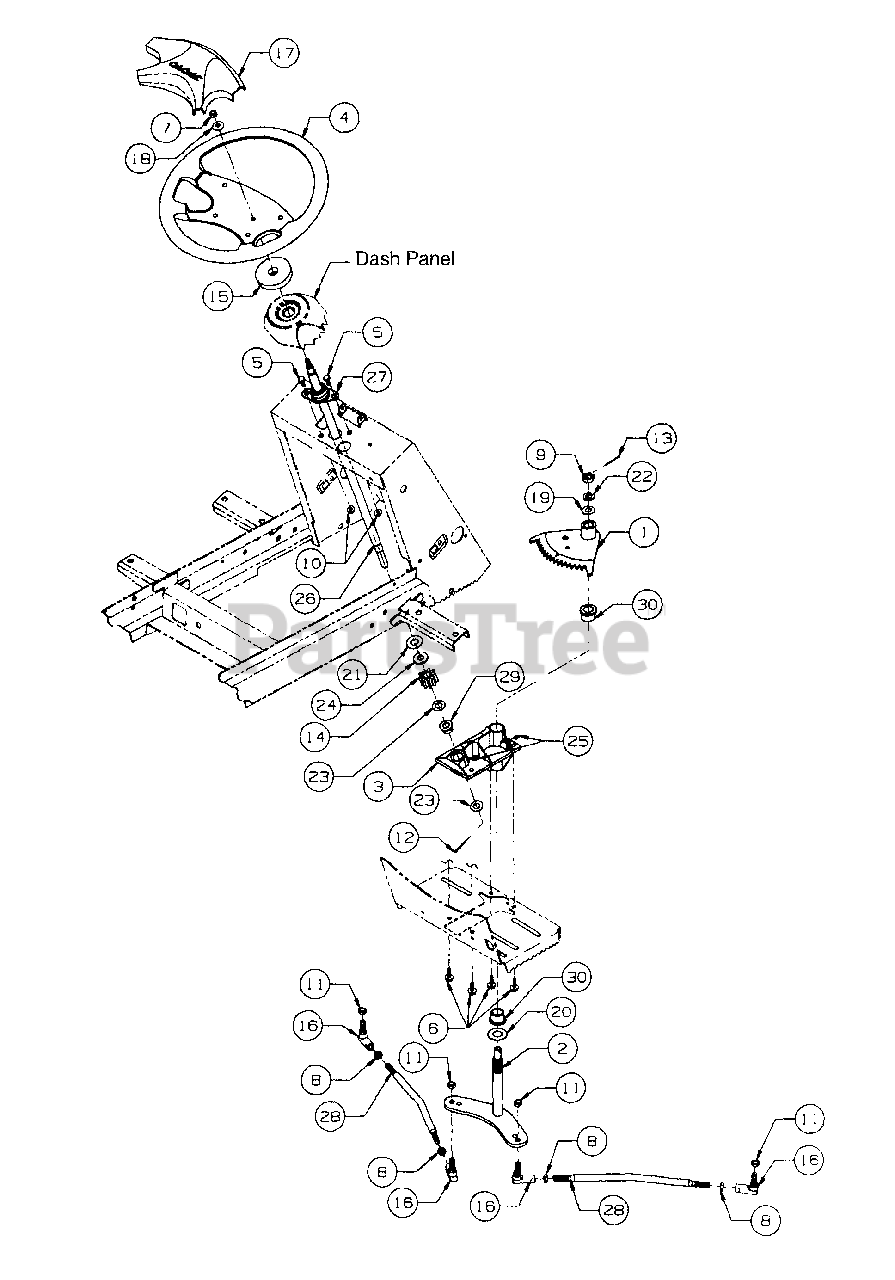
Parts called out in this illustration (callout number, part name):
1	Segment Assy, 1ST Steering
2	Arm Assy, Lower Steering
3	Housing Assy,
4	Wheel, Steering
5	Screw, Hex Cap, 1/4-20 x .62, GR5
6	Screw, Hx Wsh Hd-TPTT, 5/16-18 x .75
7	Nut, Hex Center Lock, 5/16-24
8	Nut, Hex Jam, 3/8-24 GR5
9	Nut, Hex Slotted, 1/2-20 GR5
10	Nut, Hex Flange Lock, 1/4-20
11	Nut, Hex Lock, 3/8-24 GR5
12	Pin, Cotter, 1/8 Dia x 1
13	Pin, Cotter, 3/32 Dia x 1.25
14	Pinion, Steering
15	Gasket, Steering
16	Joint, Ball, 3/8-24
17	Insert, Steering Wheel
18	Washer, Bell, .340 x .88 x .06 Thk
19	Washer, Flat, .510 x 1 x .06 Thk
20	Washer, Flat, .760 x 1.5 x .03 Thk
21	Washer, Flat, .56 x 1 x .04 Thk
22	Washer, Lock, 1/2
23	Washer, Flat, .531 x 1 x .027 Thk
24	Wshr, Rubber Flat, .50 x 1.12 x .125 Thk
25	Fitting, Grease, 3/16 Drive Type
26	Shaft, Steering
27	Bearing, Flange
29	Bearing, Flange, .503 ID
30	Bearing, Bronze Flange, .75 ID
